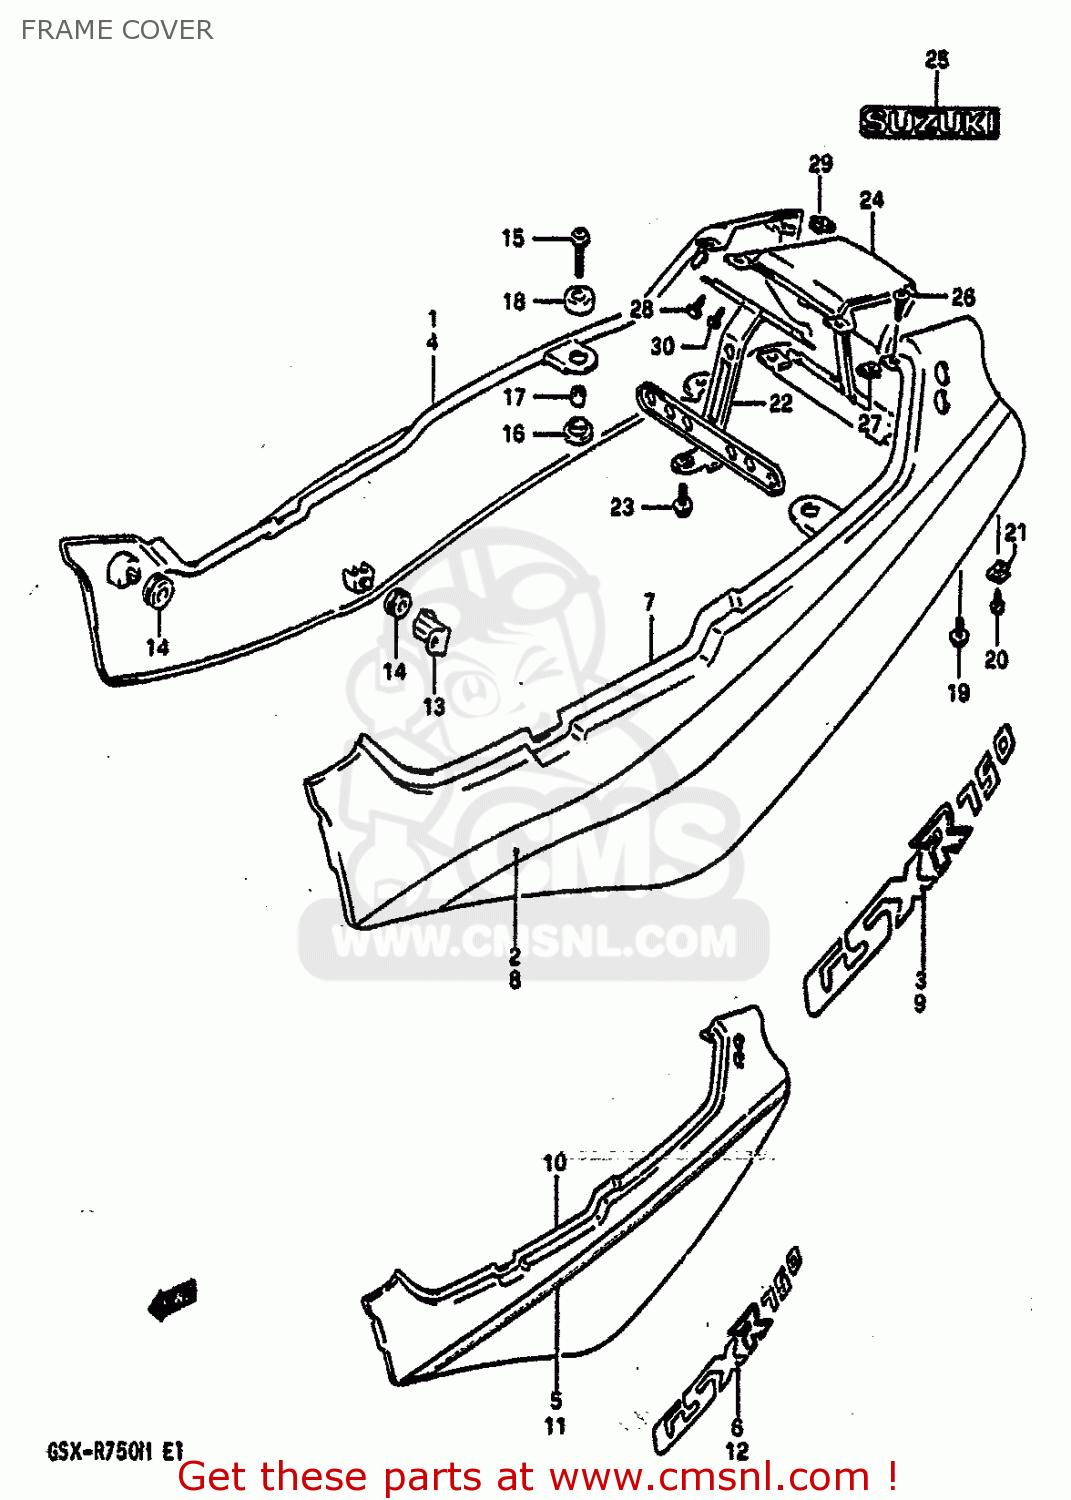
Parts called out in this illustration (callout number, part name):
1	COVER,FRAME RH
2	TAPE,RH
3	EMBLEM,FRAME COVER
4	5
5	TAPE,FRAME COVER,R
6	EMBLEM
7	COVER,FRAME LH
8	TAPE,LH
9	EMBLEM,FRAME COVER
10	COVER,FRAME LH
11	TAPE, LH
12	EMBLEM
13	BRACKET,FRAME COVER
14	CUSHION
15	SCREW (6X16)
16	CUSHION,FRAME COVER LWR
17	SPACER
18	CUSHION,TAIL COVER UPR
19	SCREW(6X30)
20	SCREW
21	NUT
22	BRACKET,TAIL LAMP
23	BOLT
24	COVER,FRAME,CT
25	EMBLEM
26	SCREW, BRACKET
27	NUT
28	SCREW, BRACKET
29	NUT
30	SCREW
